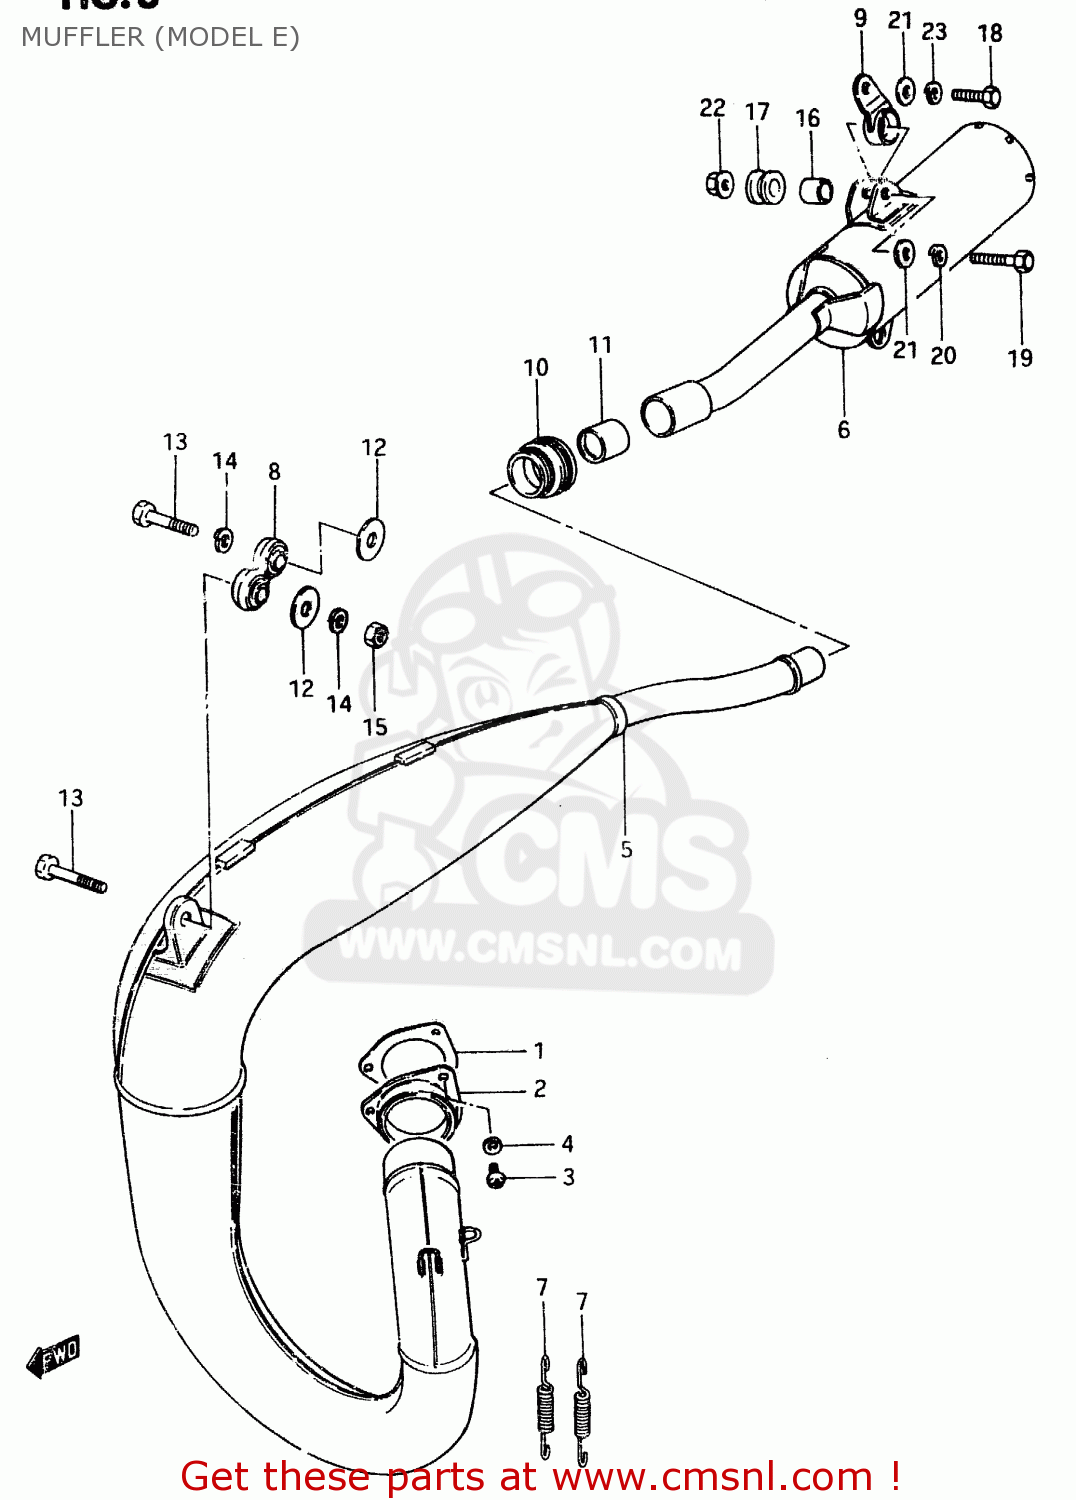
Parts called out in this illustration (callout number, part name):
1	GASKET,EXHAUST PIPE (MCA)
2	FLANGE,EXHAUST PIPE
3	SCREW
4	LOCK WASHER
5	MUFFLER, 1ST
6	MUFFLER, 2ND
7	SPRING
8	DAMPER,MUFFLER
9	DAMPER,MUFFLER SUPPORT
10	CONNECTOR,SECOND MUFFLER
11	GASKET,SECOND MUFFLER (NA) (NAS)
12	WASHER
13	BOLT(8X32)
14	LOCK WASHER
15	NUT 8MM
16	SPACER (8.6X12X17.5)
17	CUSHION
18	BOLT
19	BOLT
20	LOCK WASHER
21	WASHER
22	NUT
23	WASHER,LOCK,8.
